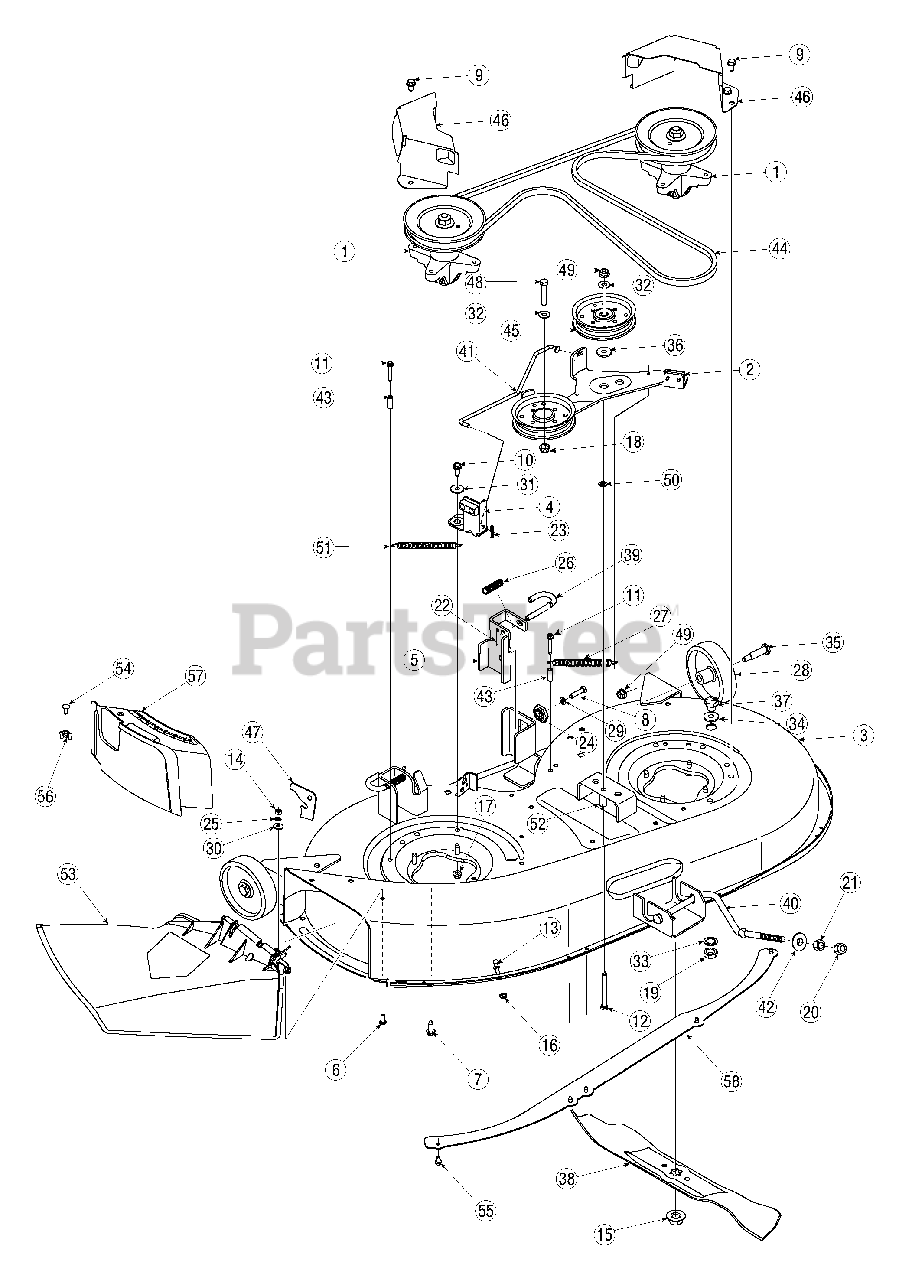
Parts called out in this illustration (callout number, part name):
1	Pulley/ Spindle Assembly
6	Screw, 1/4-20 x.620
7	Screw, 5/16-18 x.875
8	Screw, 5/16-18 x 1.25
9	Screw, 5/16-12 x.750
10	Screw, 5/16-18 x.750
11	Screw, 1/4-20 x 1.500
12	Screw, 3/8-16 x 3.50
13	Grass catcher Pin
14	Hex Nut, 1/4-20
15	Flange Nut, 5/8-18
16	Flange Lock Nut, 1/4-20
17	Flange Lock Nut, 5/16-18
18	Flange Lock Nut, 3/8-16
19	Hex Nut, M16-1.5
20	Hex Lock Nut, 1/2-13
21	Hex Nut, 1/2-13
22	Cotter Pin, 1/8 x 1.25
23	Cotter Pin,.072 Dia. x 1.13 Lg.
24	Deck Adjustment Gear
25	Push Nut,.25 ID x.50 OD
26	Compression Spring,.531 OD x 1.75 Lg.
27	Extension Spring,.50 Dia. x 6.37 Lg.
28	Deck Wheel
29	Lock Washer, 5/16
30	Bell Washer,.265 x.75 x.062
31	Shoulder Bushing,.320 ID x.135 Lg.
32	Flat Washer,.385 x.87 x.06
33	Lock Washer, 5/8
34	Flat Washer,.64 x 1.24 x.06
35	Shoulder Screw,.498 x 1.53 x 3/8-16
36	Shoulder Spacer,.8540 x.200
38	Blade, 21.23", Star 3-in-One
39	Deck Release Handle Rod
40	Front Deck Adjustment Rod
41	Brake Control Rod
42	Deck Lift Pivot Cup
43	Spacer,.260 x.372 x 1.030 Lg.
44	V-Belt, 96.3 Lg.
45	Idler Pulley, 4.25" Dia.
47	Chute Stop not used
48	Screw, 3/8-16 x 2.00
49	Flange Lock Nut, 3/8-16
50	Push Nut, 3/8
51	Extension Spring,.500 Dia. x 6.375 Lg
52	Spacer, 3/8 ID x.68 OD x 1.46 Lg
53	Discharge Chute
54	Carriage Screw, 1/4-20 x.62 If Equipped
55	Screw, 1/4-20 x.500 If Equipped
56	Wing Nut, 1/4-20 If Equipped
57	Mulch Plug If Equipped
